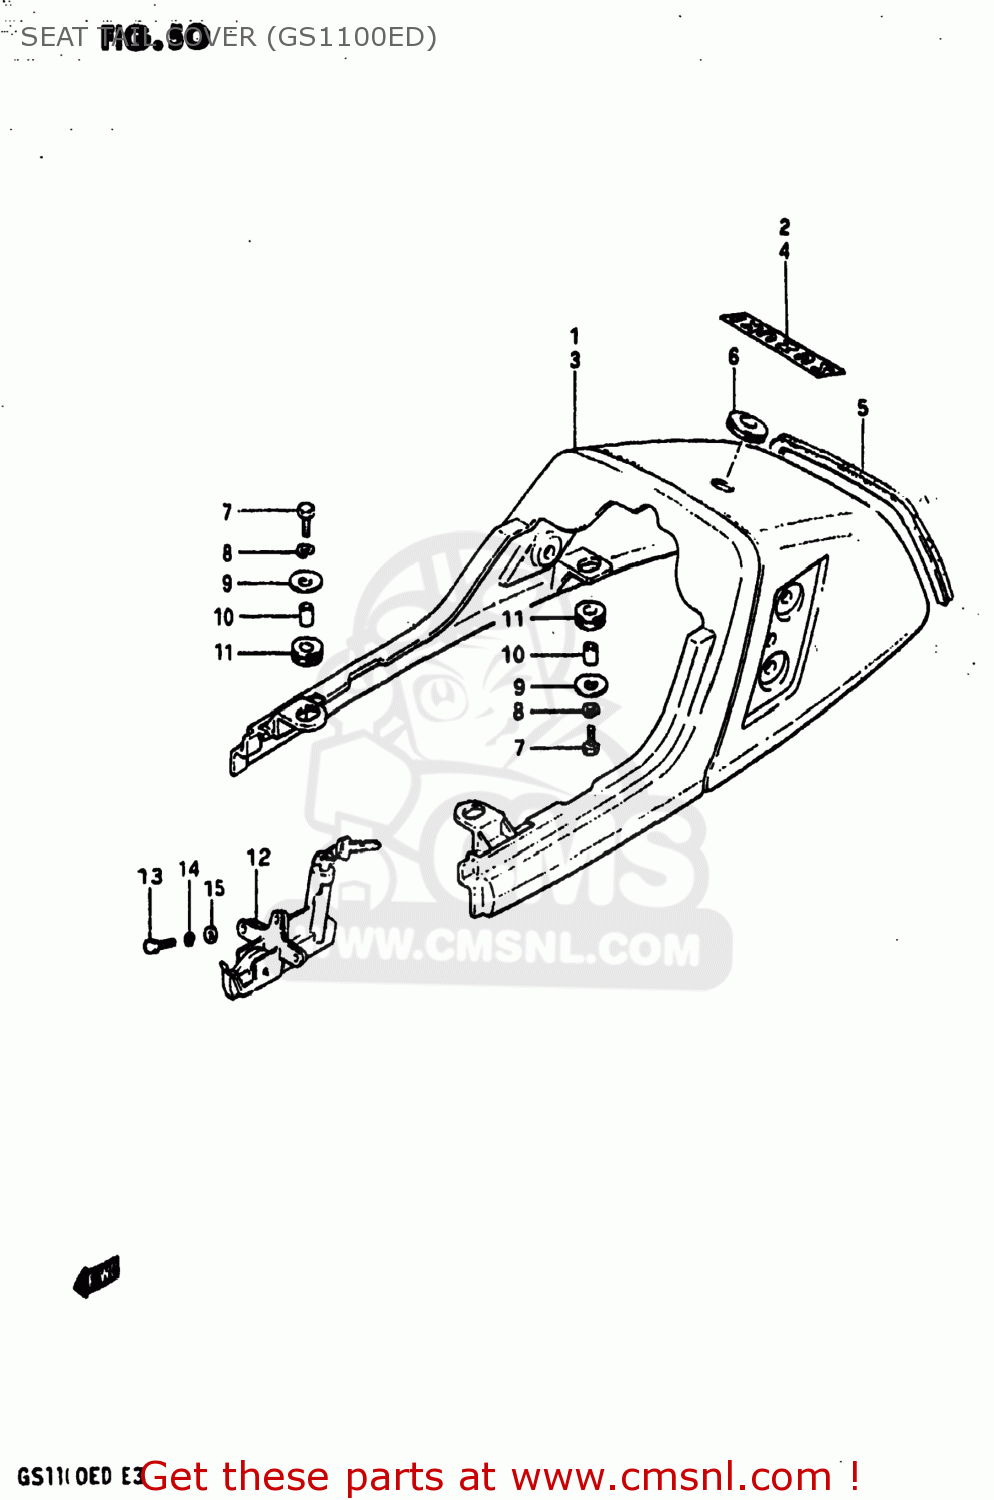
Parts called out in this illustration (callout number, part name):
1	COVER,SEAT TAIL
2	EMBLEM,SEAT TAIL COVER
3	COVER,SEAT TAIL
4	EMBLEM,SEAT TAIL COVER
5	RUBBER,BLIND,SEAT TAIL COVER
6	GROMMET,SEAT LOCK HOLE
7	BOLT
8	LOCK WASHER
9	WASHER(6,5X22X1.6)
10	SPACER(6.5X10.5X12)
11	CUSHION
12	LOCK SET,SEAT
13	BOLT
14	LOCK WASHER
15	WASHER
